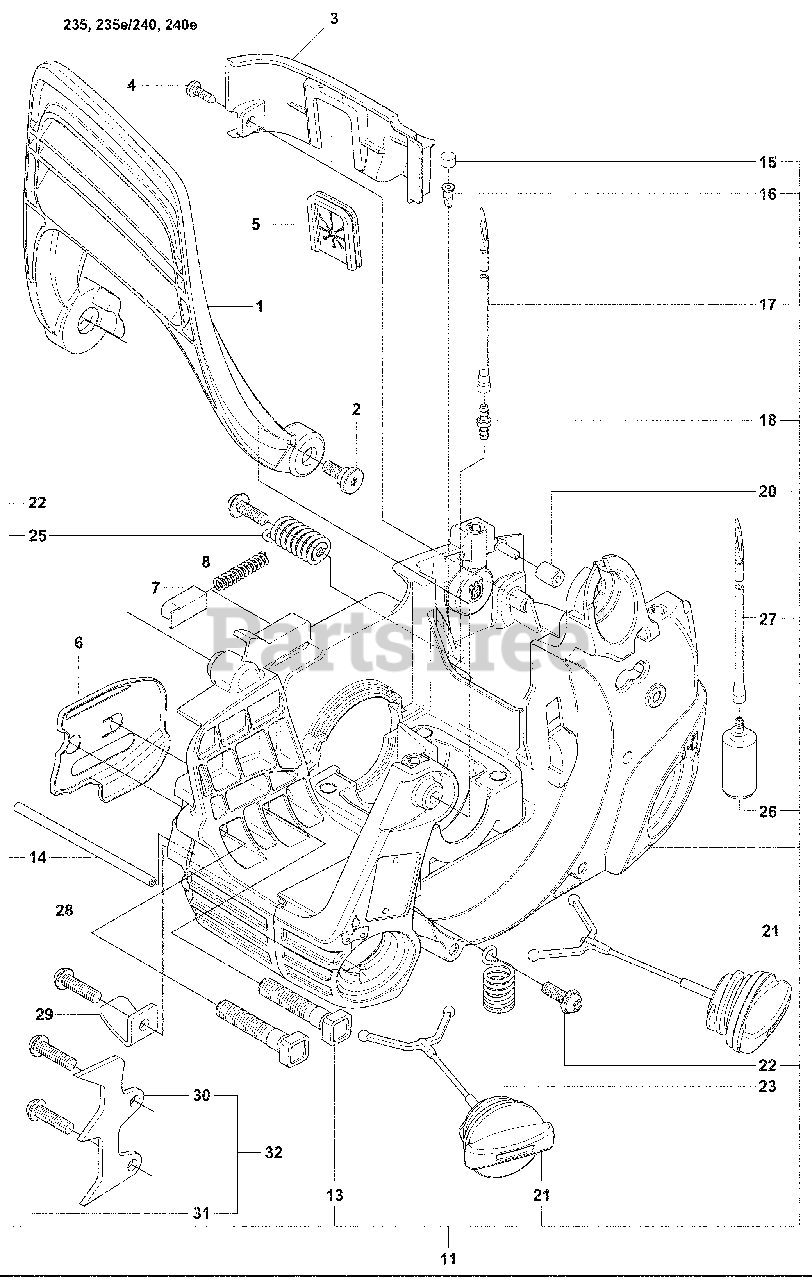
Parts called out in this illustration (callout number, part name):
1	HANDGUARD
2	BOSS SCREW, HANDGUARD
4	SCREW, MTG REAR WALL
5	GROMMET, REAR WALL
6	PLATE BAR MOUNTING
7	CAP, SPRING HANDGUARD
8	SPRING, HANDGUARD POSITION
11	CHASSIS ASSEMBLY
14	ASSY, VENT LINE
15	PLUG VENT (BRONZE)
16	CHECK VALVE (DUCK BILL)
17	LINE-RETURN PURGE
18	FITTING- FUEL LINE
20	ISOLATOR FILTER HOUSING
21	ASSY-OIL/FUEL CAP W/RET.
22	SCREW M5.28X1.81X16MM PLAS
23	ASS'Y FRONT ISOLATOR
25	REAR ISOLATOR SPRING
26	ASSY- PICK-UP
27	LINE, FUEL
28	Screw catcher
29	Chain catcher
30	SPIKE
31	SCREW SPIKE
32	KIT SPIKE
